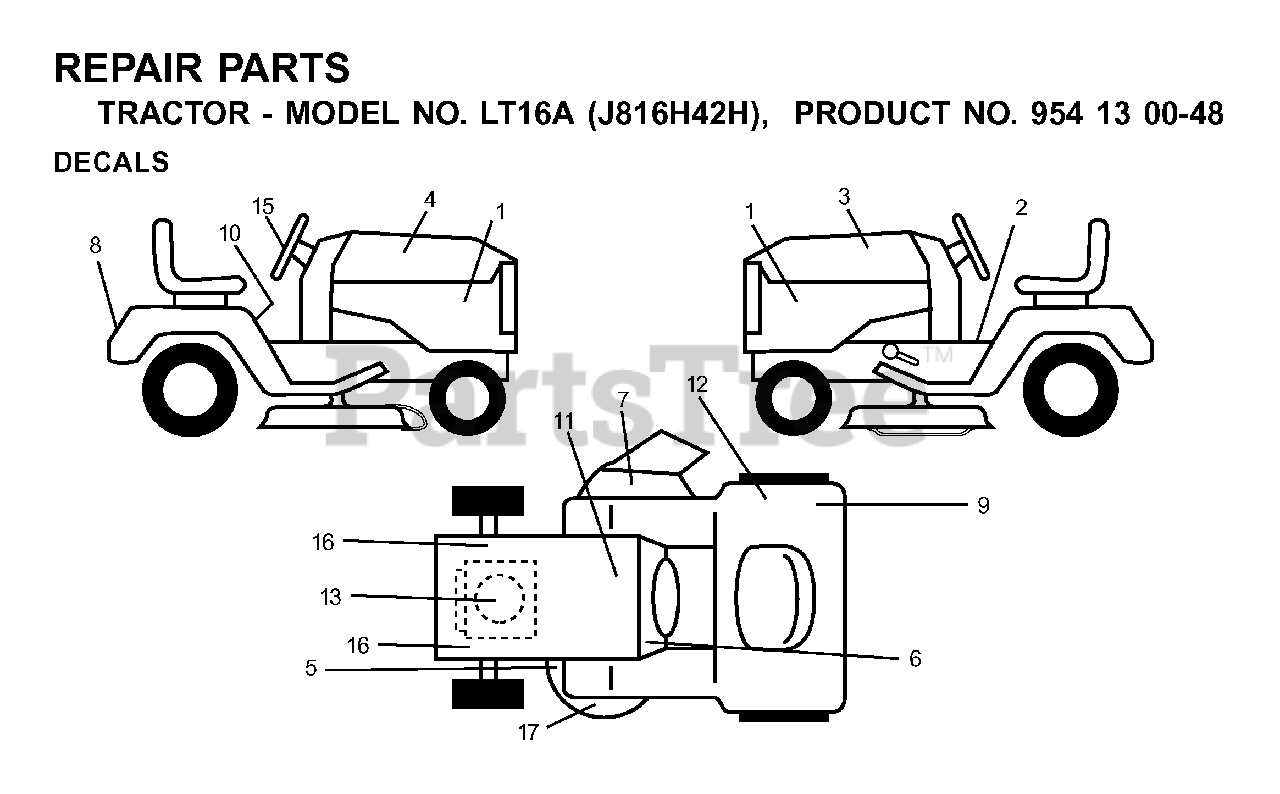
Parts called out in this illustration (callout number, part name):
2	DECAL PARK BRAKE
5	DECAL V BELT SCHEMATIC
7	DECAL MOWER CUT/FINGER
9	DECAL CERTIFICATION
10	DECAL READ OWNER'S MAN SYMS
11	DECAL BTRY SYMBOLS
12	DECAL EUROPE STANDARD CE
